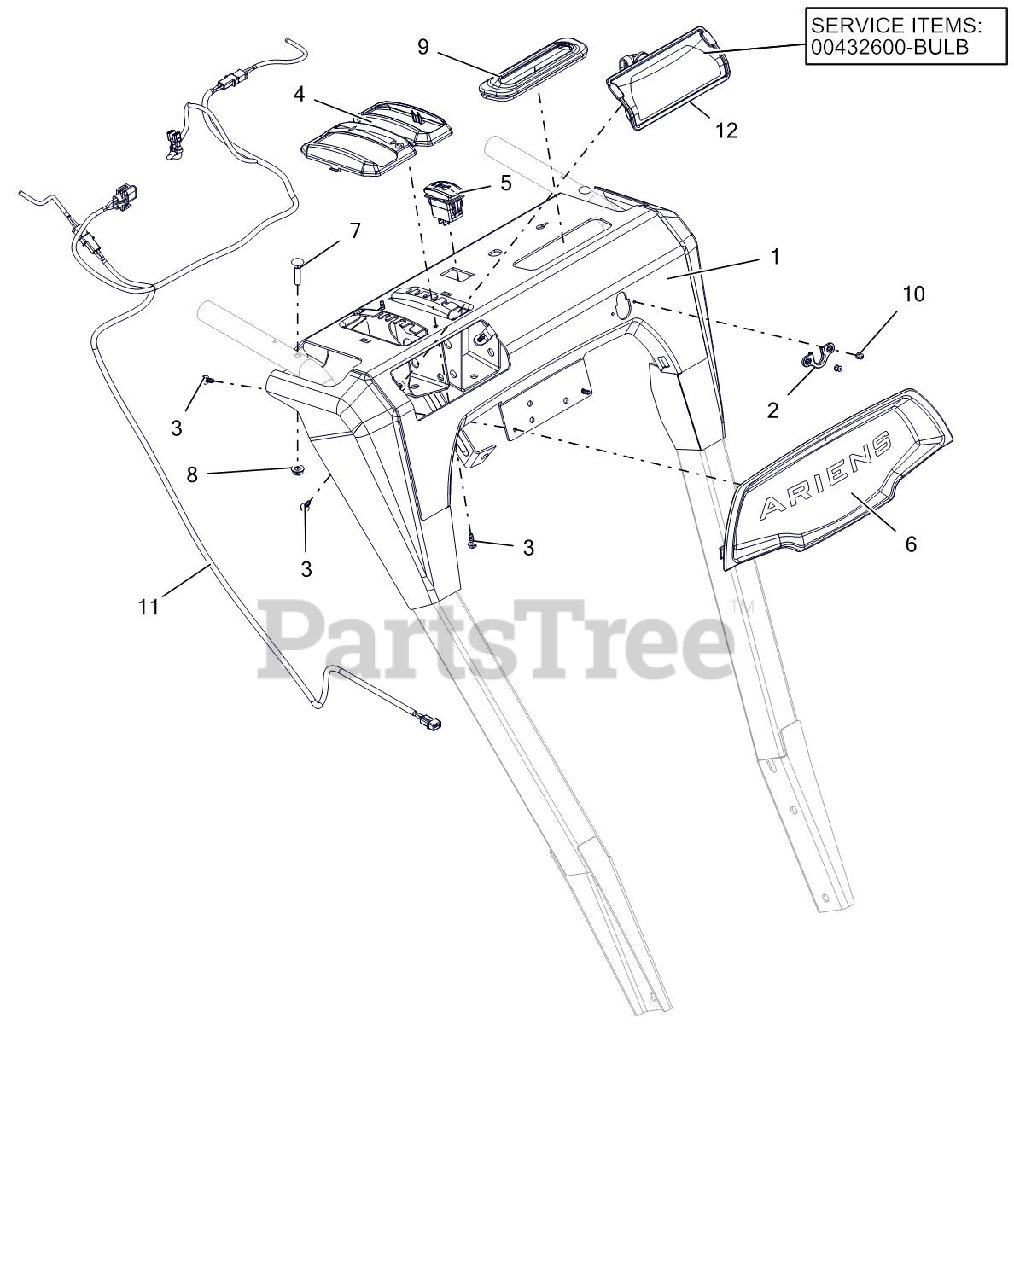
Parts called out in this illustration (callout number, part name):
1	PANEL, DASH-FRICTION W/DECAL
2	GROMMET, CABLE, QUICK TURN 2
3	SCR-TAP #10X.50 BOSS INDHXHD
4	BEZEL, SHIFT - FRICTION SNOW
5	SWITCH,ROCKER SPST-ON/OFF
6	BEZEL, DASH - ARIENS LG DASH
7	BLT-RDHDXLSQNK.25-20X1.25 G5ZC
8	@NUT-LK-CTR-FLG .25-20 YWZC
9	GROMMET, BOOT, QUICK TURN
10	RVT-POP #43 .125X.313 STL ZINC
11	HARNESS, LIGHT & WARMER
12	BULB, LIGHT-HALOGEN 20W
12	HEADLIGHT ASY, HALO 20W 2SHOT
